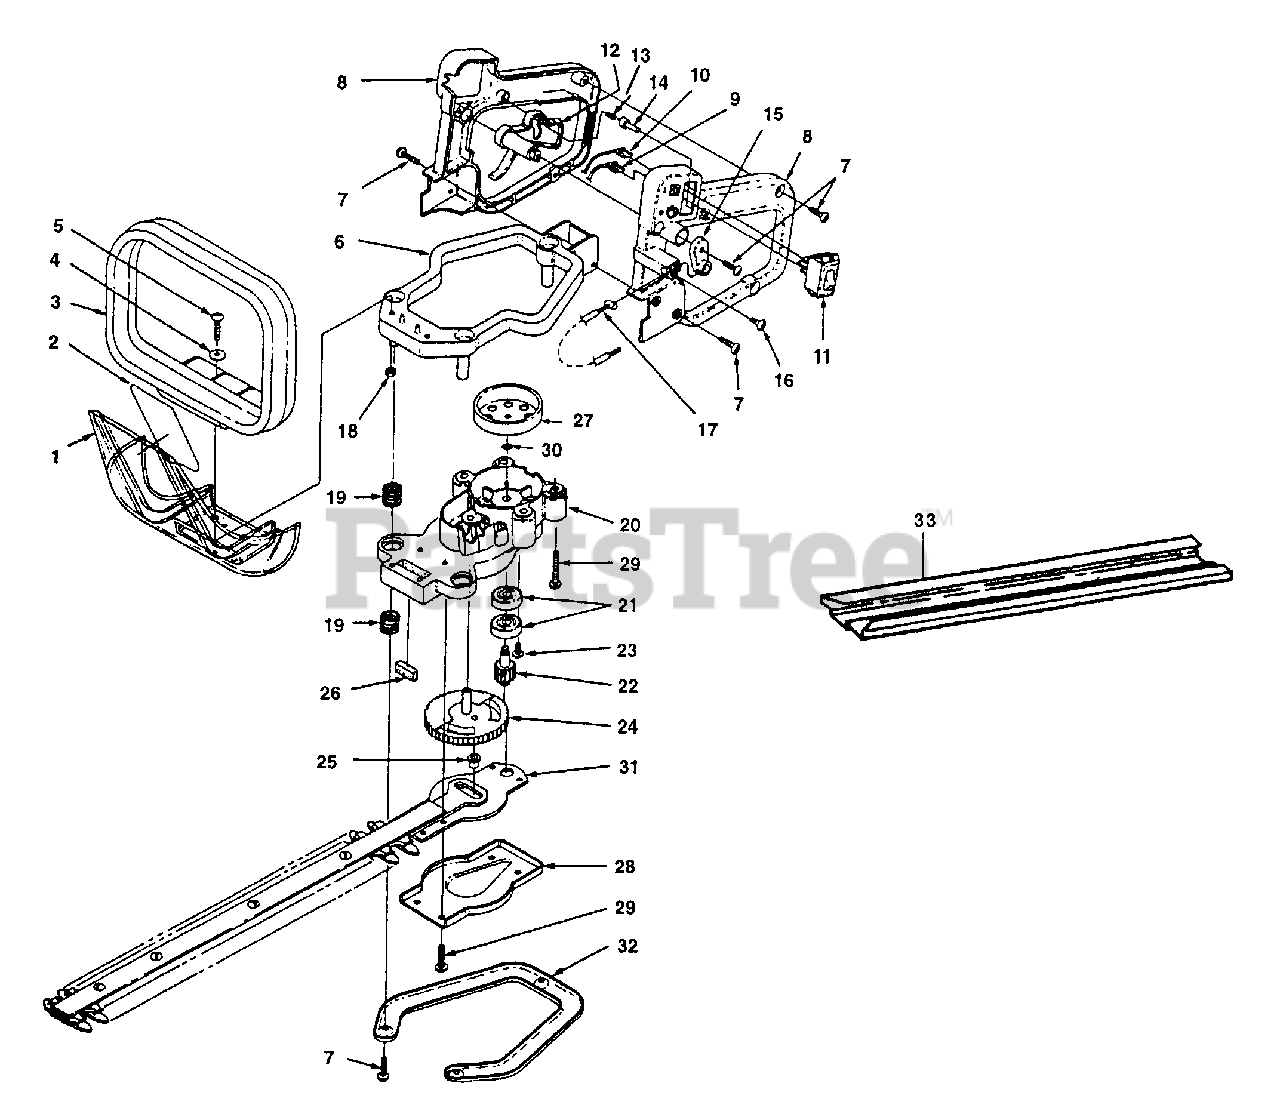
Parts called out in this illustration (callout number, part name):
1	GUARD-Hand
2	DECAL-Caution
3	HANDLE-Front
4	WASHER-Flat (10-24)
5	SCREW-Thread Form. (10-24 x 3/4")
6	BASE-Vibration Isolator
7	SCREW-Thread Form. (#8 x 3/4")
8	HANDLE Assembly
9	LEAD-Electrical
10	LEAD-Ground
11	SWITCH
12	TRIGGER
14	BUTTON-Lock
15	LEVER, Trigger
16	SCREW-Thread Form. (#10 x 1/2")
17	CABLE-Throttle
18	NUT-Hex (10-24)
19	SPRING-Compression
20	GEAR BOX ASSEMBLY
21	BEARING-Ball
22	PINION & SCREW ASSEMBLY
23	SCREW-Thread Form. (#10 x 1/2")
24	GEAR & PIN ASSEMBLY
25	BUSHING
26	BLADE-Seal
27	DRUM-Clutch
28	COVER-Gear Box
29	SCREW-Thread Form. (#10 x 7/8")
31	BLADE ASSY (17")
33	GUARD-Blade (17")
